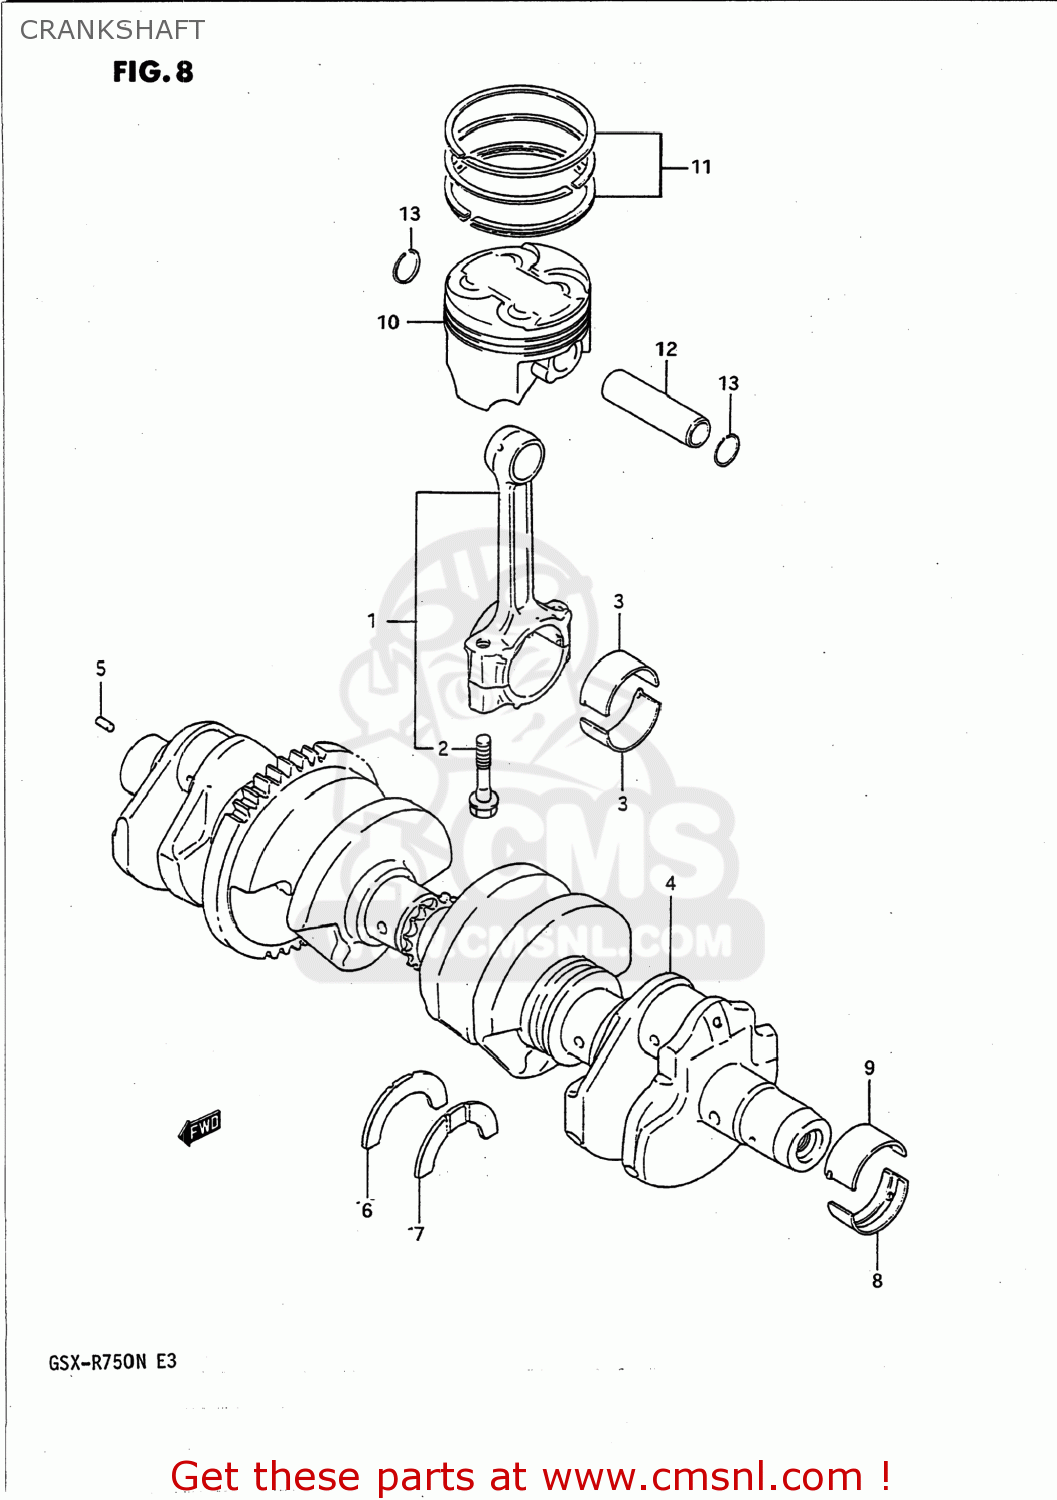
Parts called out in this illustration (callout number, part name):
1	ROD ASSEMBLY,CONNECTING
2	BOLT,CONNECTING ROD
3	BEARING,CRANK PIN
4	CRANKSHAFT SET
5	PIN
6	PLATE,CRANK THRUST
7	PLATE,CRANK THRUST
8	BEARING,CRANKSHAFT LWR
9	BEARING,CRANKSHAFT UPR
10	PISTON
11	RING SET,PISTON
12	PIN,PISTON
13	CIRCLIP
